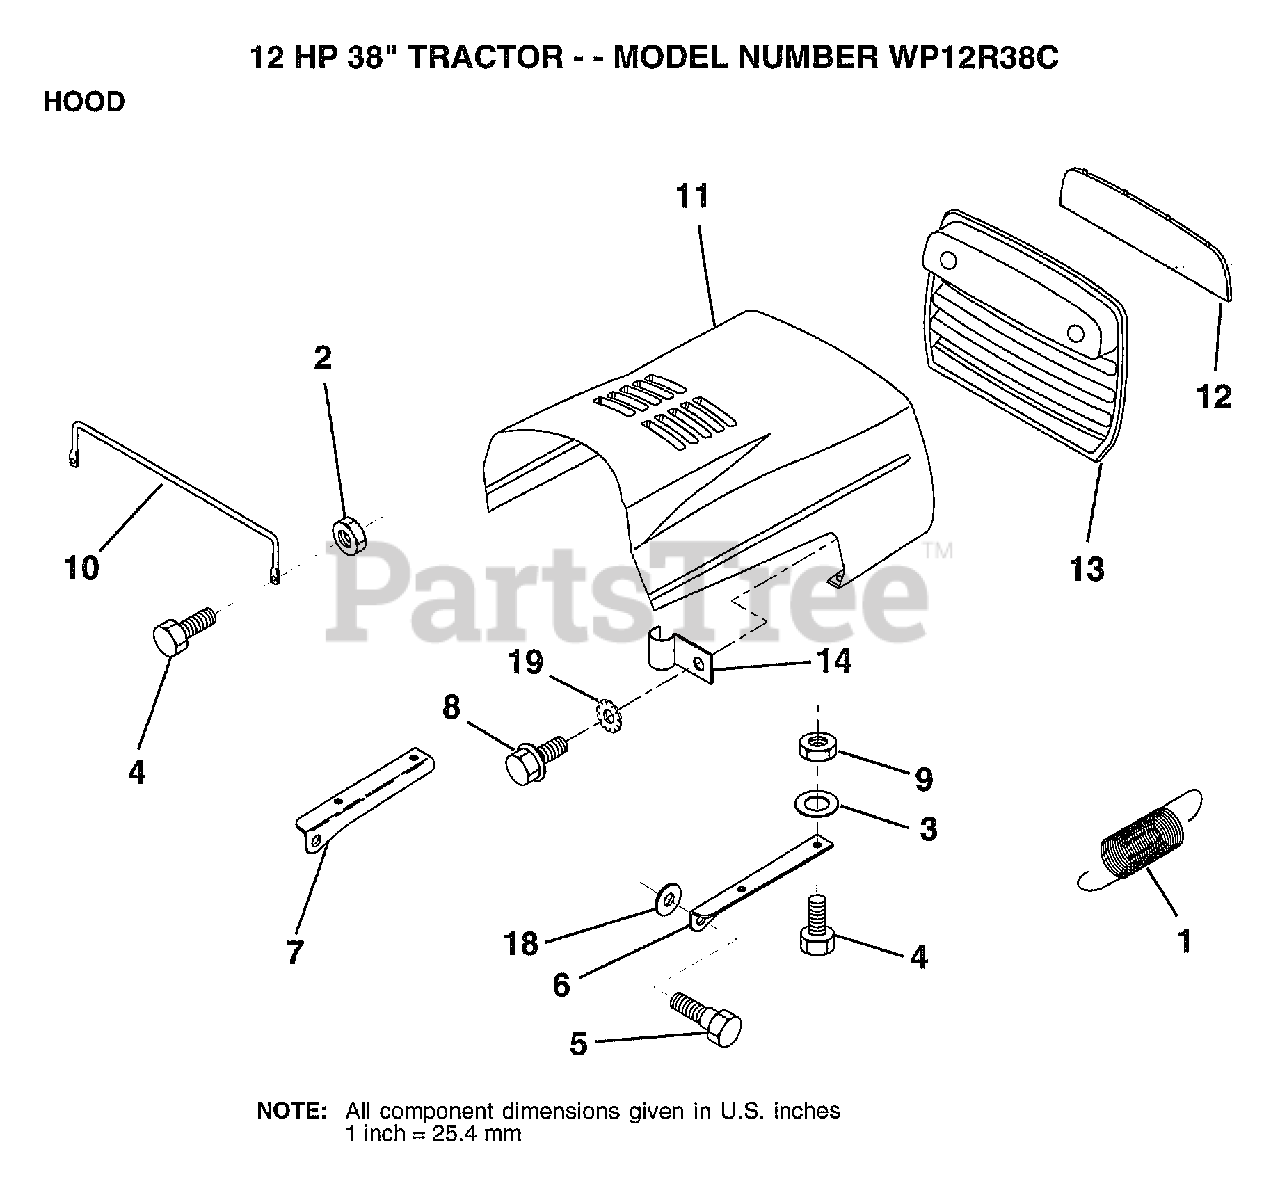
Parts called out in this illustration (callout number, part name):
1	EXT SPRING
2	NUT
3	WASHER
6	BRKT HOOD RH
7	BRKT HOOD LH
8	SCREW SLTD HXHD
9	NUT
10	"BRACE,HOOD"
11	HOOD
12	LENS
13	GRILL
14	CLIP T
18	WASHER
19	LOCKWASHER GT
